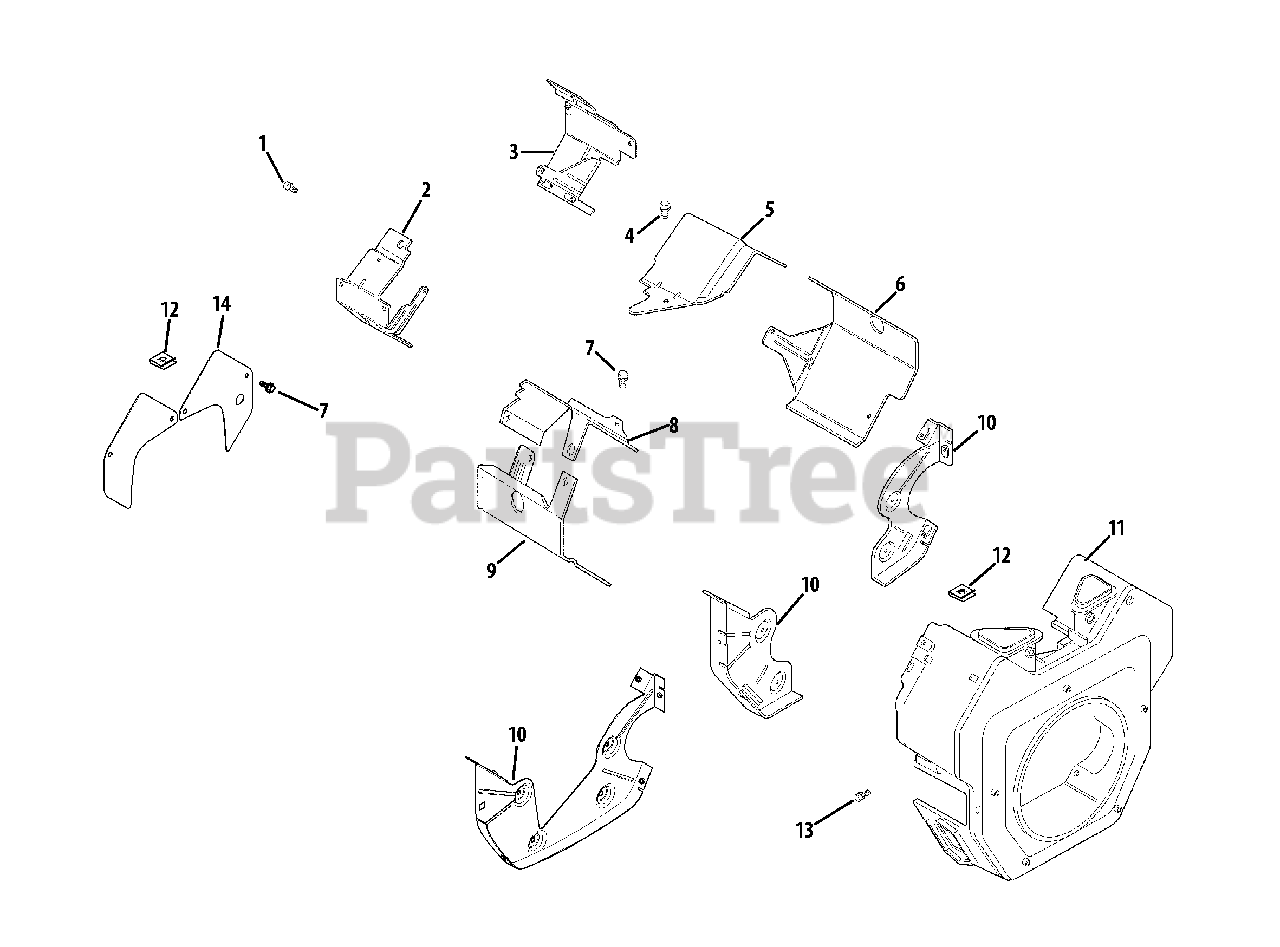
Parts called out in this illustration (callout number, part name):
1	Flange Screw, M6 x 1.0 x 10
2	Ducted Air-Oil Filter Baffle
3	Ducted Air-Starter Baffle
4	Thread Forming Screw
5	Valley Baffle, #1 Cylinder
6	Cylinder Baffle Kit, #1 Side
7	Thread Forming Screw
8	Valley Baffle, #2 Cylinder
9	Cylinder Baffle Kit, #2 Side
10	Backing Plate Kit
11	Blower Housing Assembly Kit
12	Baffle Mounting Clip
13	Thread Forming Screw
14	Access Panel Kit
